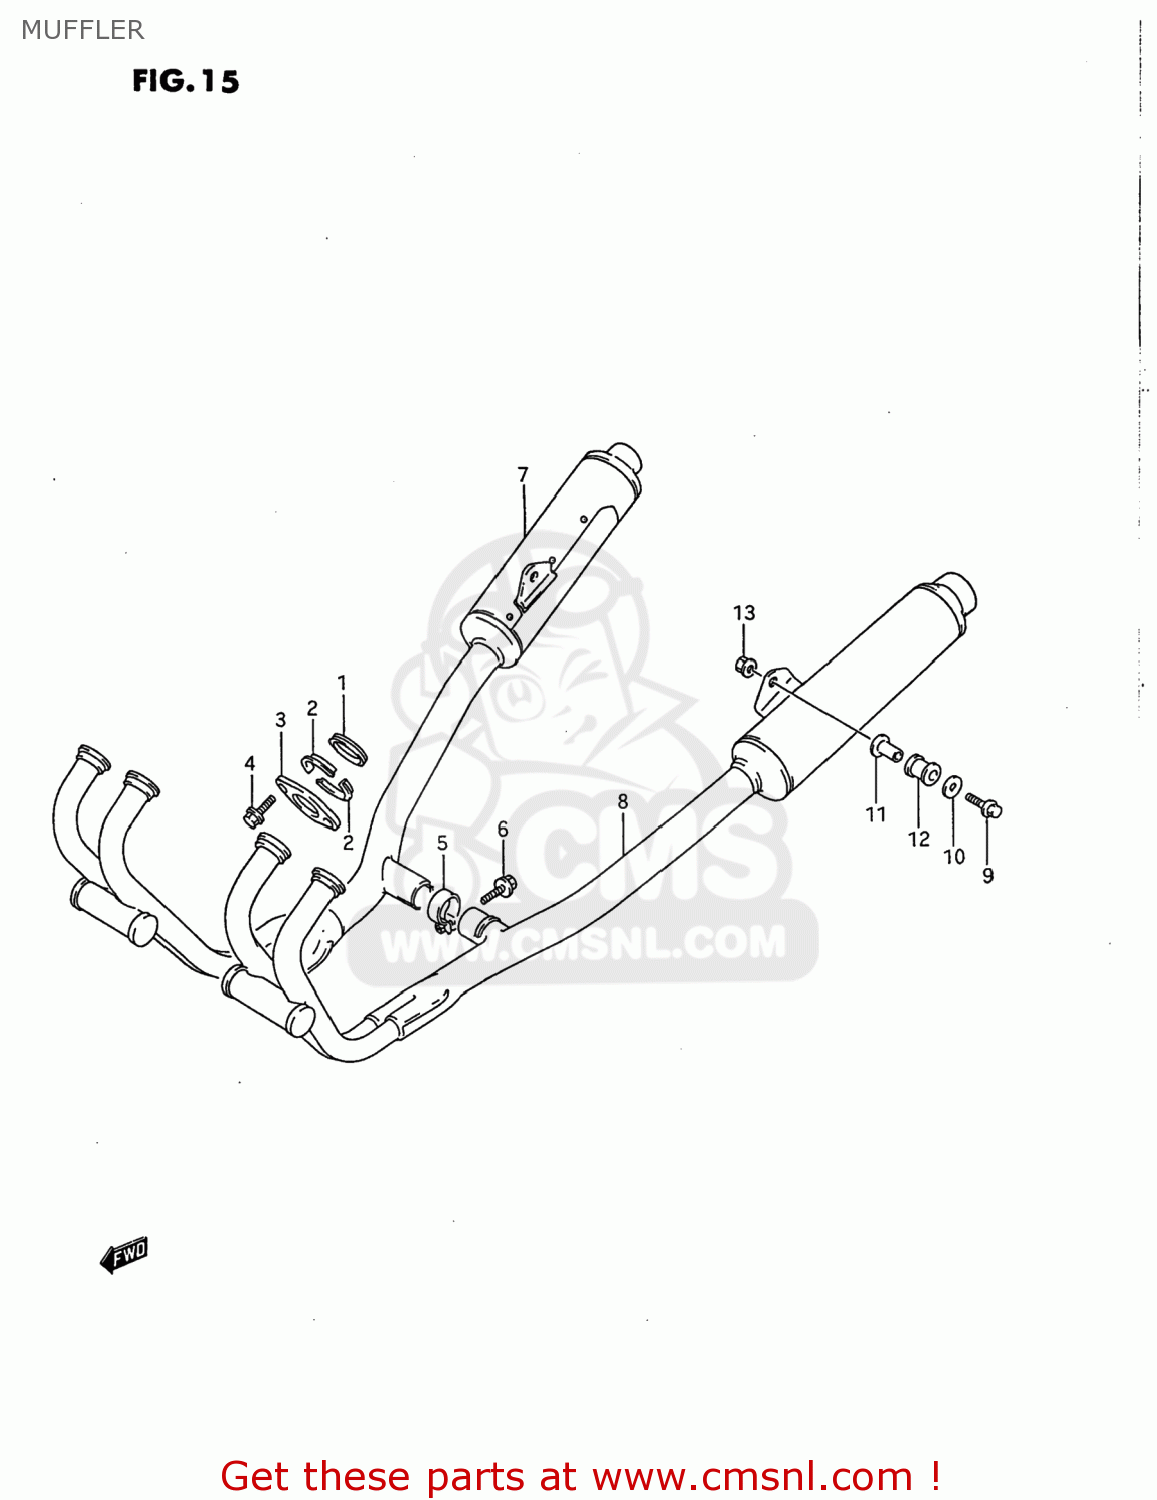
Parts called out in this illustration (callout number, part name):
1	GASKET,EXHAUST (NAS)
2	PLATE,EXHAUST PIPE
3	CLAMP,EXHAUST PIPE
4	BOLT
5	CLAMP,MUFFLER CONNECTOR
6	BOLT
7	MUFFLER COMP,RIGHT
8	MUFFLER COMP,LEFT
9	BOLT(8X40)
10	WASHER (8.1X33X1.6)
11	SPACER(8.6X12X27.1)
12	CUSHION
13	NUT
